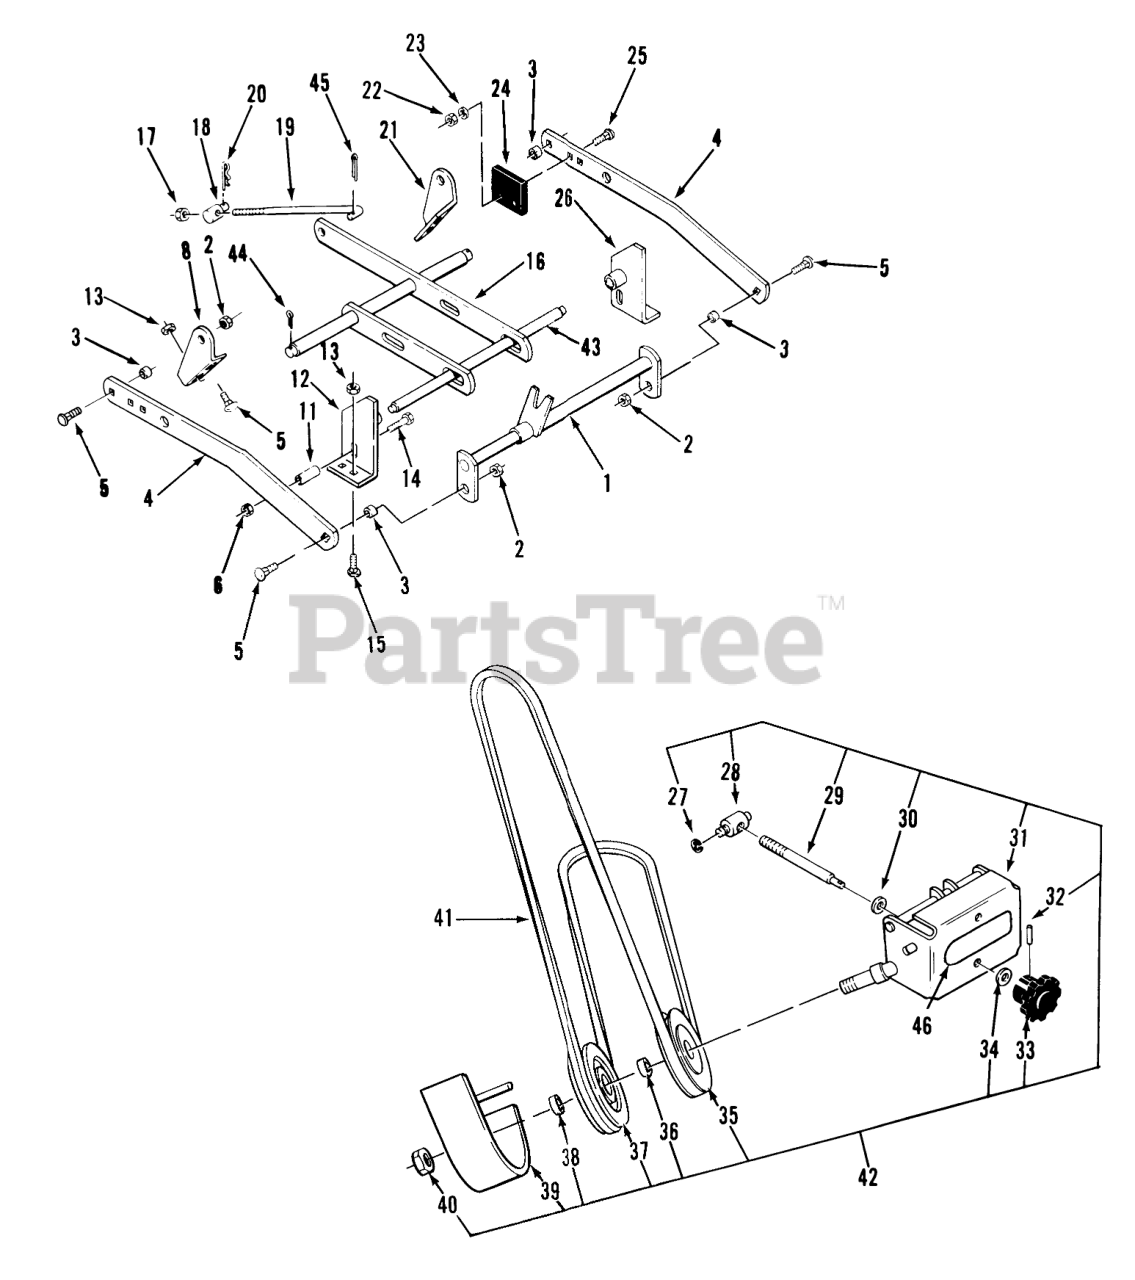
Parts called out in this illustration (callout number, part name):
1	PLATE HOODSTAND B
2	LOCKNUT-FLANGE
3	SPACER
4	Bar Draft
5	BOLT-CARR
6	Nut
8	Bracket-Rt. Rear
12	Bracket-R.H.
13	NUT-LOCK, NI
14	BOLT-CARR
15	BOLT-CARR
16	Leveler
17	NUT-LOCK, NI
18	TRUNNION-LIFT
19	Lift Rod
20	Hairpin
21	Bracket-L.H. Rear
22	NUT-LOCK, NI
23	WASHER-FLAT
24	BUMPER
25	SCREW-CARR
26	Bracket-L.H.
27	RING-RETAINING
28	TRUNNION-DOUBLE
29	ROD ADJ
30	WASHER-FLAT
31	Front Support
32	PIN-ROLL
33	KNOB-ADJUSTMENT
34	WASHER-SPRING
35	Pulley-V
36	SPACER
37	PULLEY-FLAT IDLER
38	SPACER-OUTER
39	Belt Cover
40	Nut
41	V-BELT
42	ASM-SUPPORT,IDLER
43	Front Shaft
44	PIN-COTTER
45	PIN-COTTER
46	Decal-Attac-O-Matic
